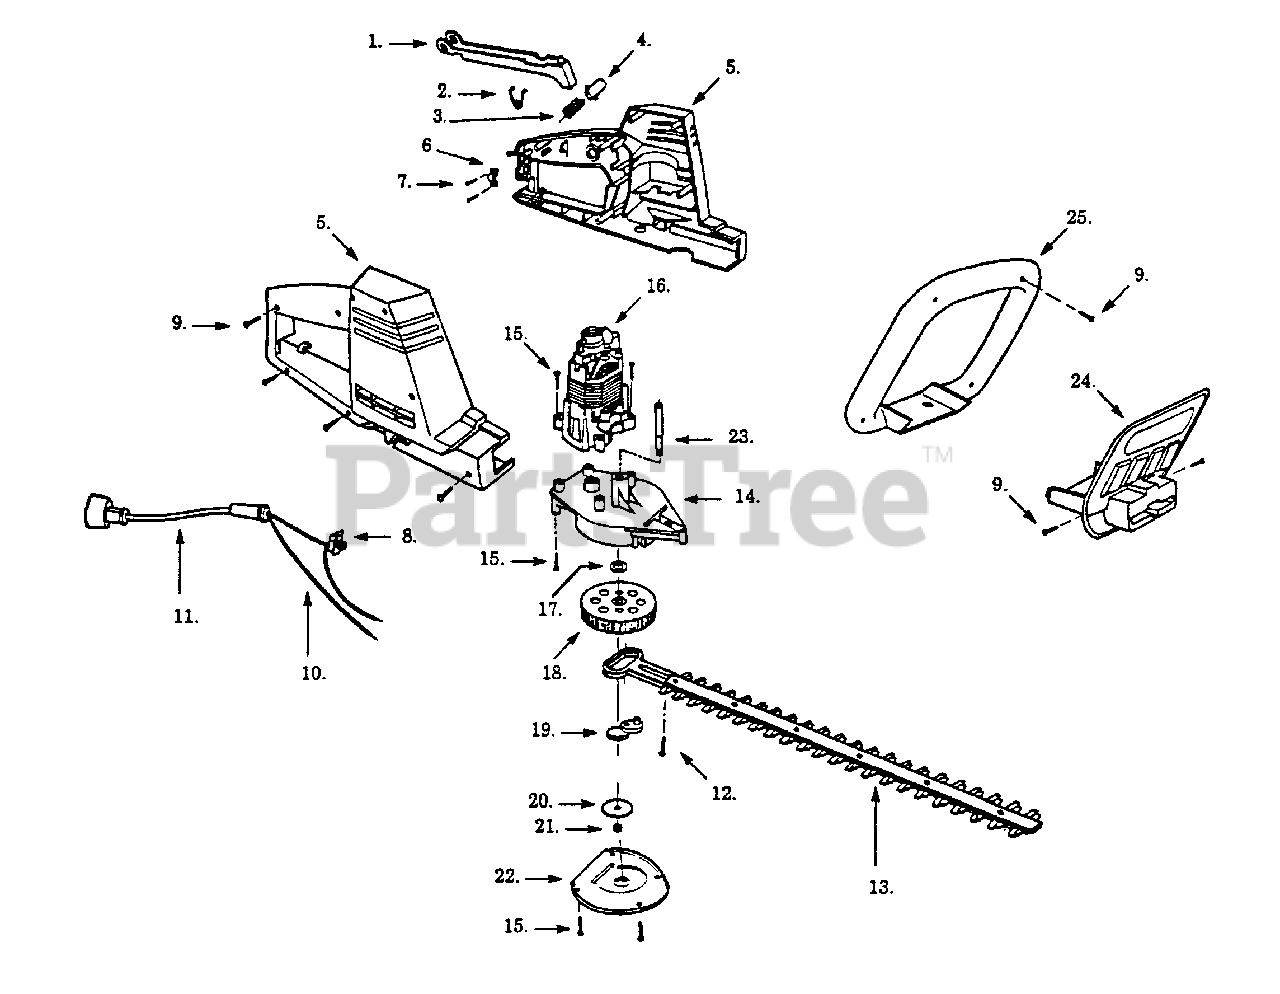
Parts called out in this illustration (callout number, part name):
1	Trigger Switch
2	Spring Clip
3	Spring-Trigger Lock
4	Button-Trigger Lock
5	Housing Set (R&L)
6	Cordset Clamp
8	Switch (On/Off)
10	Harness Ass'y.
13	Blade Ass'y.
14	Gear Box Ass'y.
16	Motor Ass'y.
22	Plate Cover
25	Handle Ass'y.
